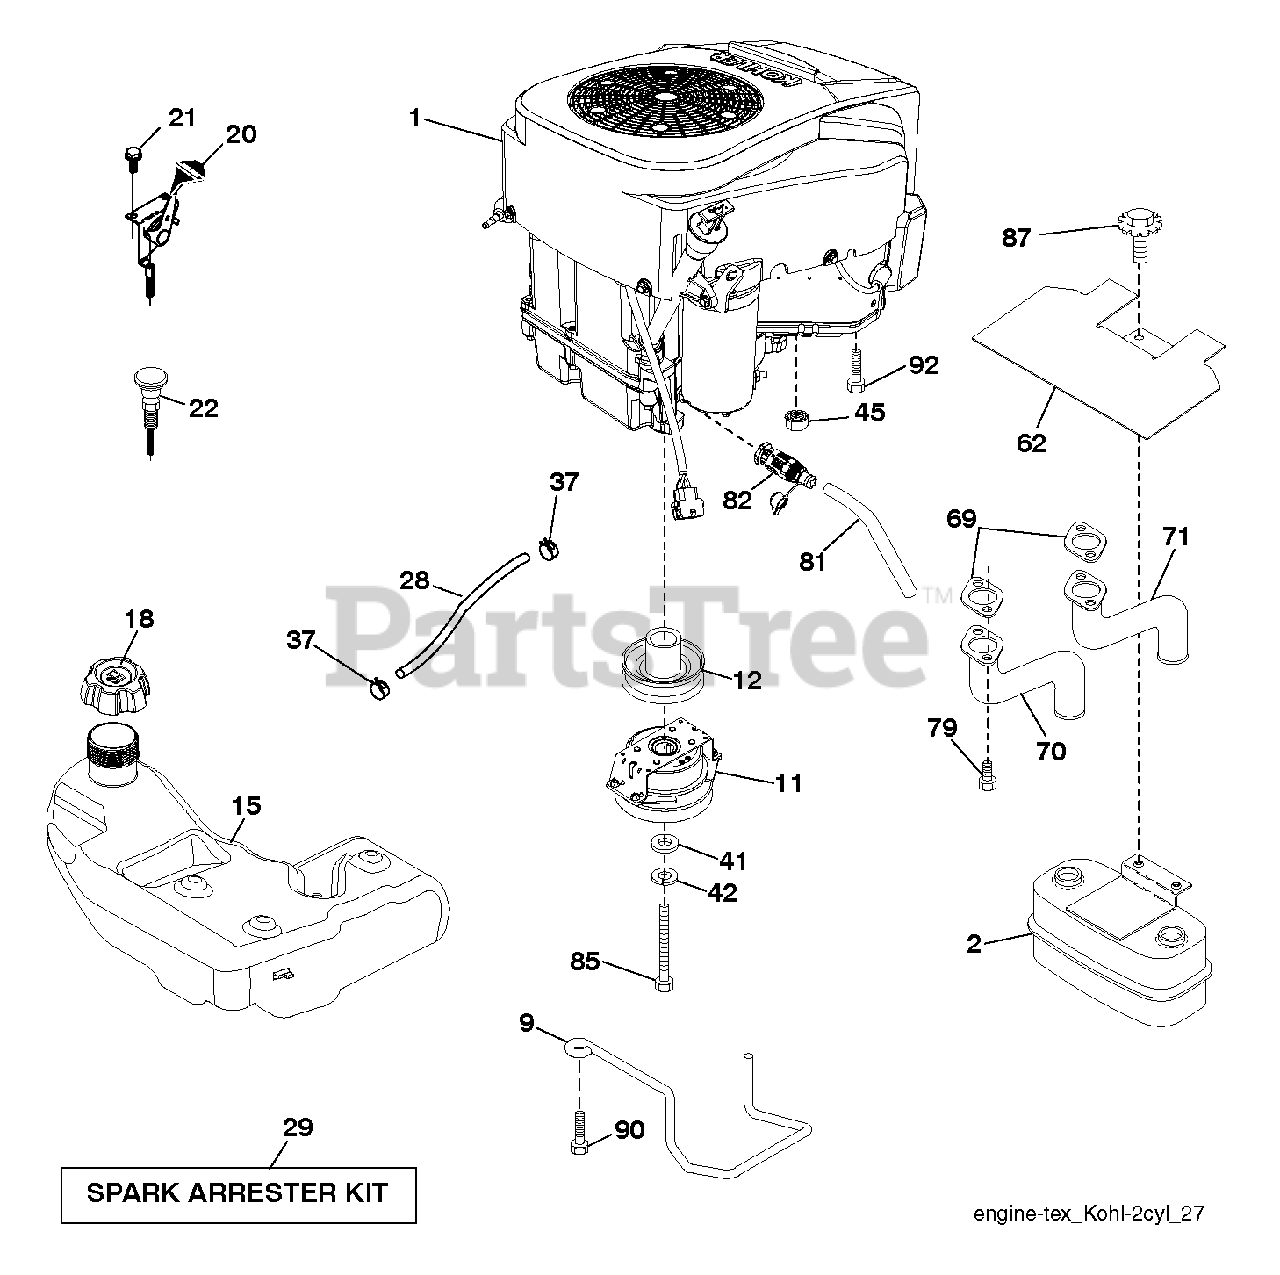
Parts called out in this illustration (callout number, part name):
2	MUFFLER.TWIN.CYL.LOW.TONE
9	Belt Keeper, 4 25"2 Blt 431
11	Clutch, Ogura 5.0Pd Gt1.5A-Eh07
12	PULLEY.ENGINE.TUFFTORQ
15	TANK.ASSY.3.GAL.EPA
18	Fuel Cap Assembly, 3" Black
20	THROTTLE CONTROL
21	SCREW.#10 X 0.750.BOS THREAD
22	CONTROL CHOKE
28	LINE.FUEL.64"REAR.EMIS
29	ARRESTER SPARK (OPTIONAL)
37	HOSE CLAMP
42	LOCKWASHER
45	NUT
62	SHIELD.HEAT.MUFFLER
69	GASKET.EXHAUST.KOHL.CV18-CV26
70	Exhaust Pipe, LH CV18/20
71	Exhaust Pipe, RH CV18/20
79	SCREW.SOCKET HD.5/16-1
81	TUBE, DRAIN OIL ASM.
82	VALUE.OIL.DRAIN
85	BOLT HEX 7/16-20 X 3.75 GR. 5
87	BOLT 5/1618UNC X 3/4 W/ SEMS
90	SCREW 3/8-16X1
92	SCREW 3/8-16X1
